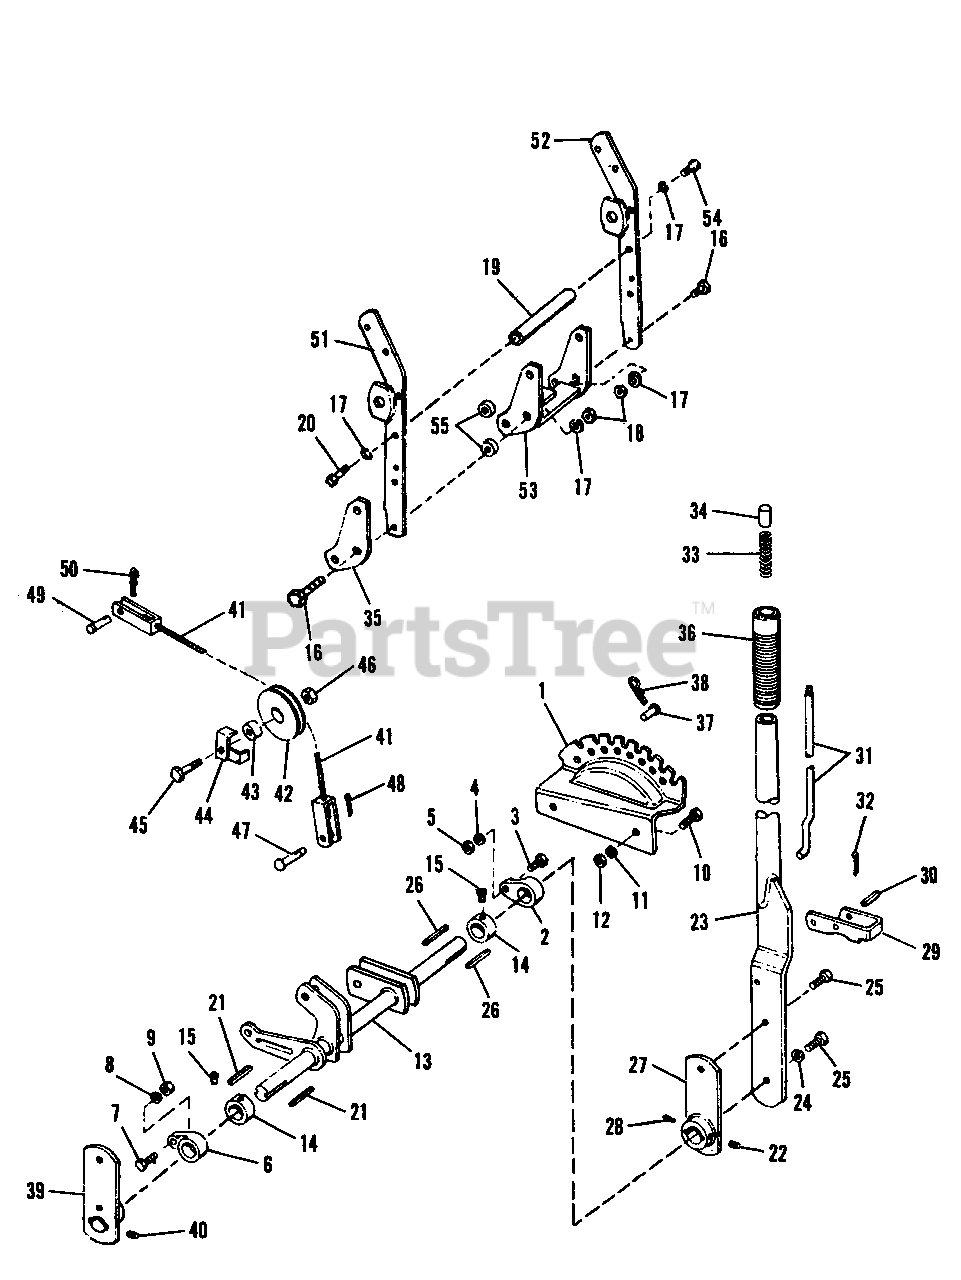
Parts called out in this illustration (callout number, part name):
1	QUADRANT, Lift Lever
2	BEARING, Lift Lever
3	CAPSCREW, Hex, 5/16"-18 x 1-1/4" lg.
4	LOCKWASHER, 5/16"
5	NUT, Hex, Full, 5/16"-18
6	BEARING, Lift Lever
7	CAPSCREW, Hex, 5/16"-18 x 1-1/4" lg.
8	LOCKWASHER, 5/16"
9	NUT, Hex, Full, 5/16"-18
10	CAPSCREW, Hex, 3/8"-16 x 3/4" lg.
11	LOCKWASHER, 3/8"
12	NUT, Hex, Full, 3/8"-16
13	SHAFT ASSEMBLY, Lift
15	SCREW, Set, 5/16"-18 x 3/8" lg.
16	CAPSCREW, Hex, 7/16"-14 x 2-3/4" lg.
17	LOCKWASHER, 7/16"
18	NUT, Hex, Full, 7/16"-14
20	CAPSCREW, Hex, 7/16"-14 x 1-3/4" lg.
22	SCREW, Set, 5/16"-18 x 1/4" lg.
23	LEVER ASSEMBLY, Lift
24	LOCKWASHER, 3/8"
25	CAPSCREW, Hex, 3/8"-16 x 1
27	LEVER ASSEMBLY, Lift
28	SCREW, Set. 5/16"-18 x 1/4" lg.
29	LATCH, Lift Lever
30	PIN, Roll, 3/8" x 1-1/4" lg.
31	ROD, Latch
32	PIN, Cotter, 3/32" x 3/4" lg.
34	BUTTON, Thumb
35	PLATE, Drain
36	GRIP, Handle
38	CUP, Spring
39	LEVER ASSEMBLY, Front Lift
40	SCREW, Set, 5/16"-18 x 1/4" lg.
41	CABLE ASSEMBLY, Lift
44	GUARD, Cable
46	NUT, Hex, Lock, Jam, 3/8"-16
47	PIN
48	PIN, Cotter, 3/32" x 7/8" lg.
50	CLIP, Spring
51	BAR ASSEMBLY, Upright
52	BAR ASSEMBLY, Upright
53	BAR ASSEMBLY, Draw
54	CAPSCREW, Hex, 7/16"-14 x 1-1/4" lg.
